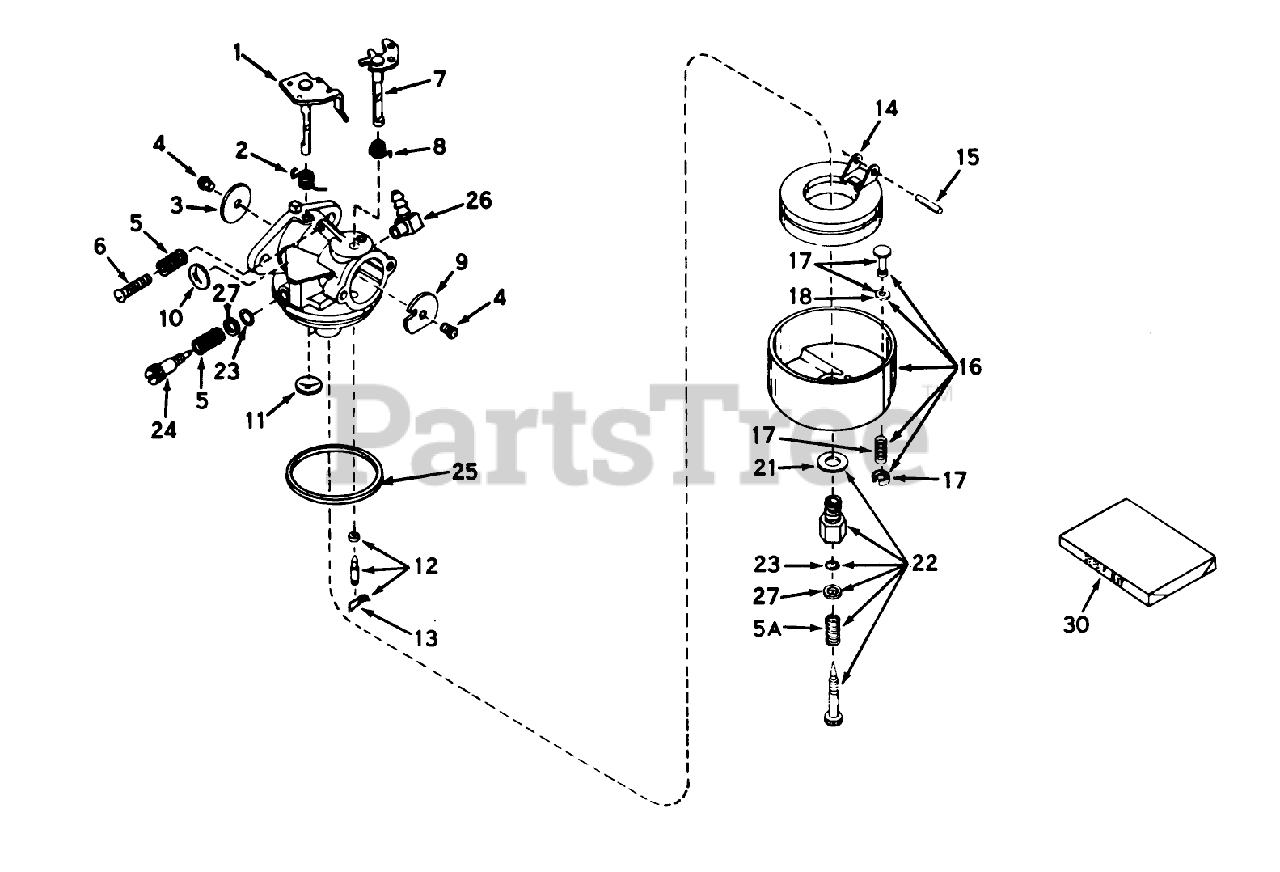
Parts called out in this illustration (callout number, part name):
1	Throttle Shaft and Lever ASM
2	Spring, Throtte Return
3	Shutter-Throttle
4	Screw-Shutter
5	Spring-Tension
5A	Spring
6	Screw-Throttle Crack Screw / Idle Speed
7	Shaft Lever Assy., Choke
8	Spring, Choke return
9	Shutter, Choke
10	Plug-Welch, Idle Mixture Well
11	Plug-Welch, Atmospheric Vent
12	Inlet Needle, Seat Clip Assy. (Incl. No. 13)
13	Clip-Spring
14	Float,Carburetor
15	Shaft-Float
16	Bowl Drain Assy., Float (Incl. No. 17)
17	Bowl Drain ASM
18	Gasket-Plunger, Drain
21	Washer-Bowl Nut
22	Adjustment Screw Assembly, Main (Incl. Nos. 5A, 21, 23 27)
23	ORing
24	Screw, Idle Adj.
25	O Ring-Bowl, Float
26	Fitting, Fuel Inlet
27	Washer
30	Repair Kit
